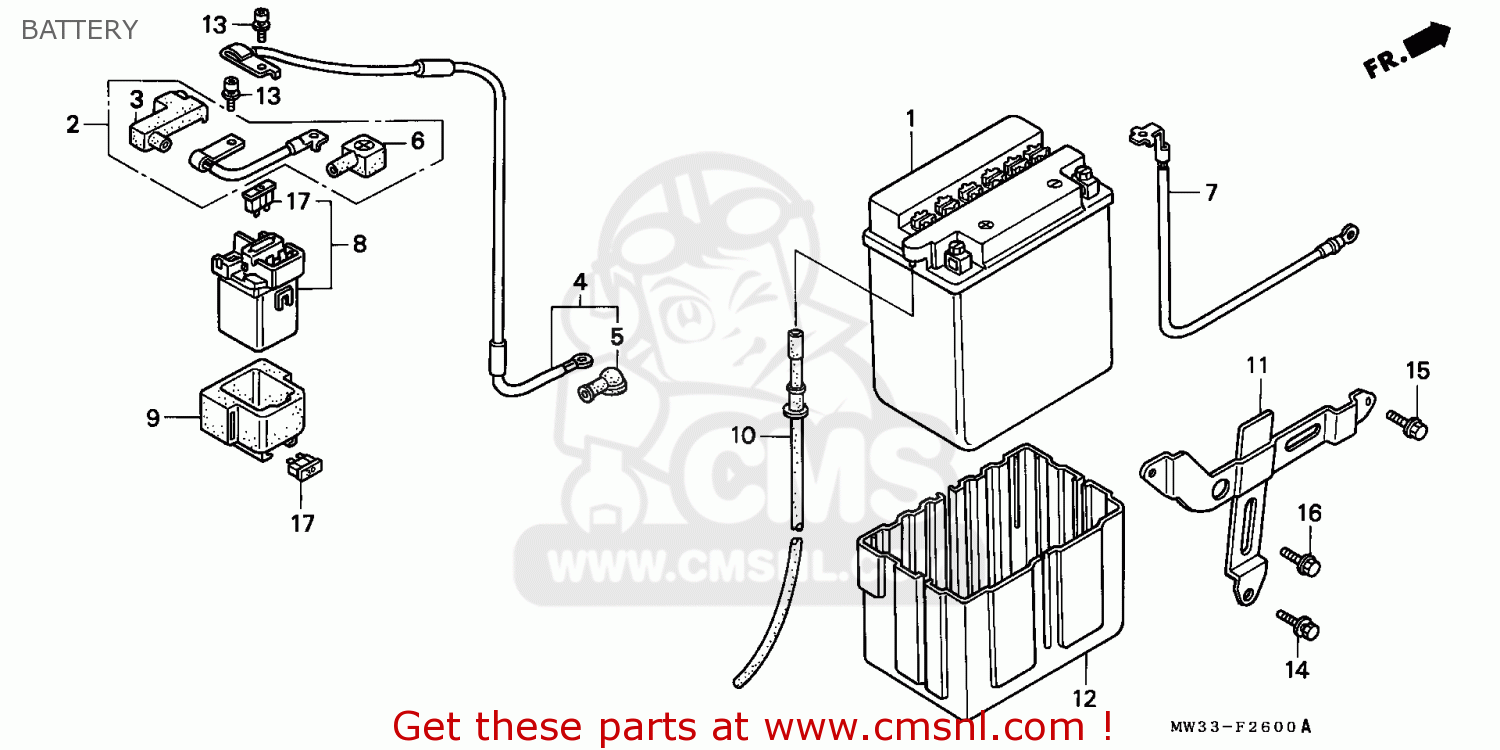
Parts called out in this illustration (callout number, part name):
1	BATTERY YB14-A2
2	CABLE,START BAT.
3	COVER STMG SW TER
4	CABLE,START MOTOR
5	COVER TERMINAL
6	COVER B,TERMINAL
7	CABLE,BAT.EARTH
8	SWITCH ASSY.,STAR
9	RUBBER,SHOCK
10	TUBE,BATTERY
11	BAND COMP,BATT.
12	CUSHION,BATTERY
13	BOLT,SOCKET,5X9
14	BOLT WASH.,6X12
15	BOLT WASH.,6X12
16	BOLT,FLANGE,6X16
17	BLADE FUSE 30A
